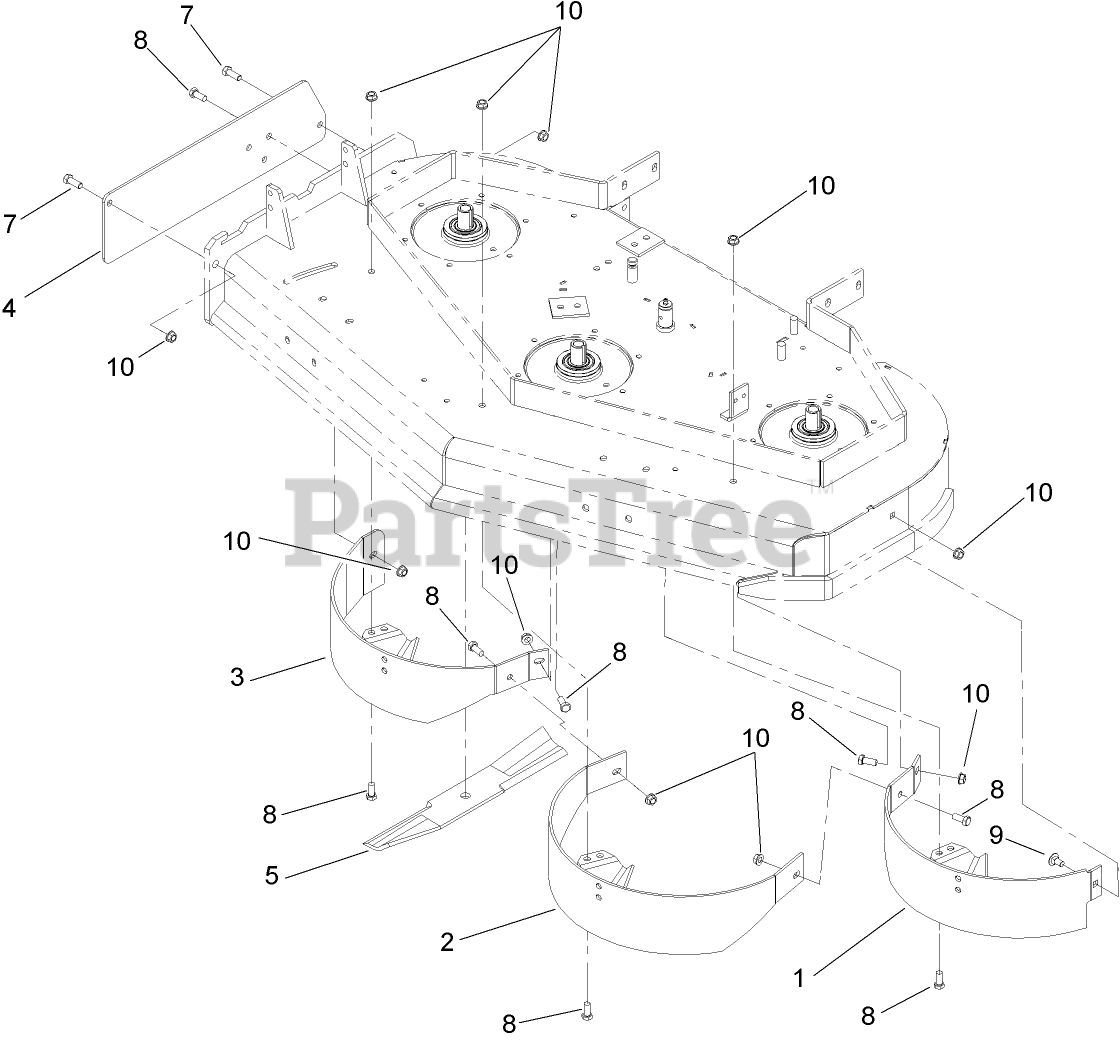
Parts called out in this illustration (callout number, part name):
1	LH BAFFLE ASM
2	CENTER BAFFLE ASM
3	RH BAFFLE ASM
4	PLATE-DISCHARGE
5	BLADE-RECYCLER, 16.5 INCH
7	SCREW-HH
8	SCREW-HH
9	SCREW-CARR
10	NUT-HHF, WHIZ
